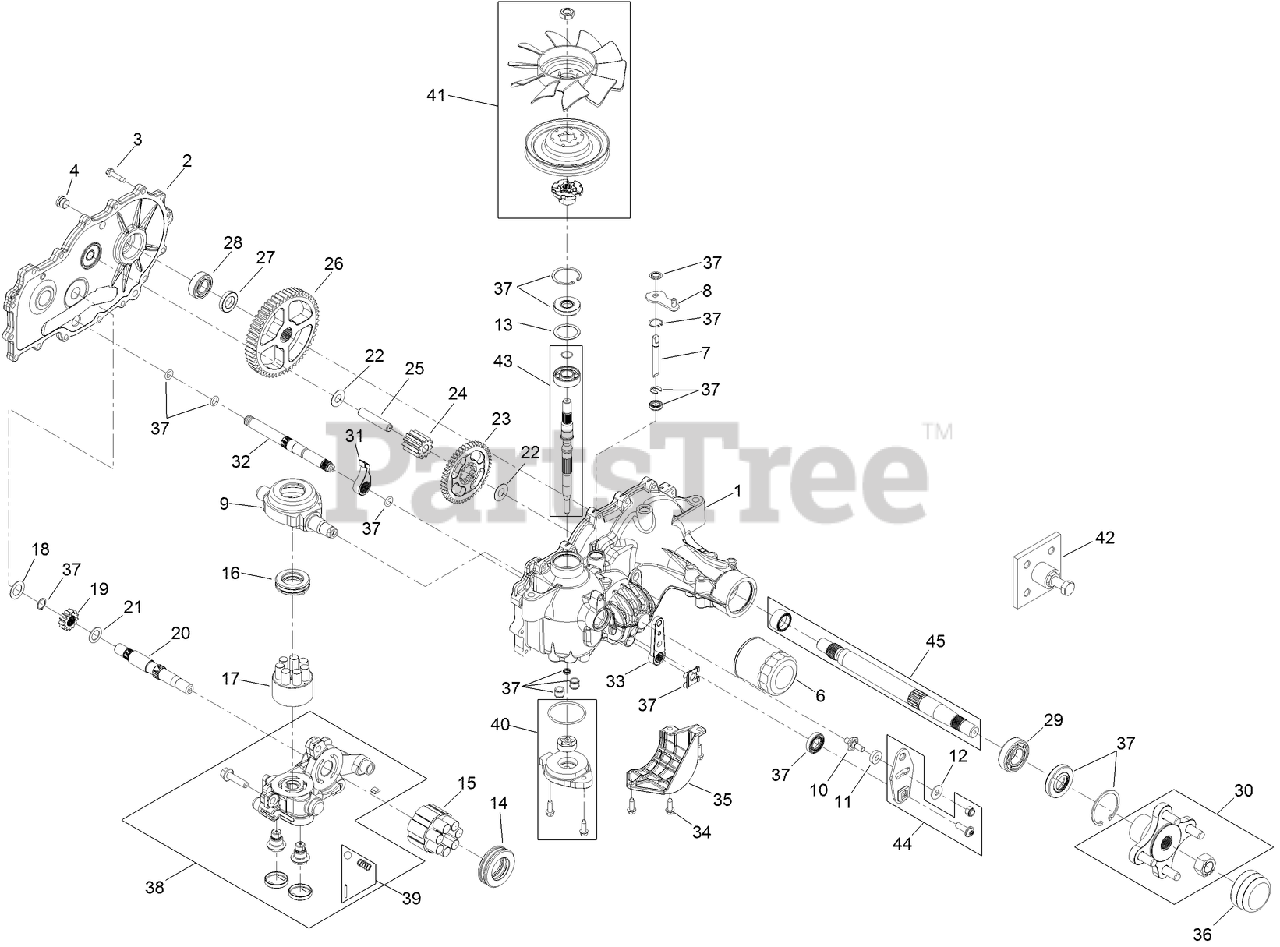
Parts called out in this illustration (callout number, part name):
1	LH MAIN HOUSING KIT
2	LH SIDE COVER KIT
3	SCREW-HHF
4	PLUG-THREAD, STRAIGHT
6	ELEMENT-OIL FILTER, HYD
7	ROD-BYPASS
8	ARM-BYPASS
9	SWASHPLATE-TRUNNION
11	PUCK-FRICTION
12	WASHER
13	SPACER
14	Bearing-Thrust
15	MOTOR CYLINDER BLOCK KIT
16	BEARING-THRUST
17	PUMP BLOCK ASM
18	WASHER-FLAT
19	GEAR-13T
20	SHAFT-MOTOR
21	WASHER
22	WASHER
23	GEAR-46T
24	GEAR-11T
25	PIN-JACKSHAFT
26	GEAR-54T
27	SPACER
28	BEARING-BALL
29	BEARING-BALL
30	HUB KIT
31	PAWL-BRAKE
32	SHAFT-BRAKE, INBOARD
33	HANDLE-BRAKE
35	GUARD-FILTER, LH
36	COVER-NUT, AXLE
37	SEAL KIT
38	LH CENTER SECTION CHARGE KIT
39	CHARGE RELIEF KIT
40	CHARGE KIT
41	FAN AND PULLEY KIT
42	PULLER-HUB, 4 BOLT
43	INPUT SHAFT KIT
44	CONTROL ARM KIT
45	AXLE SHAFT KIT
